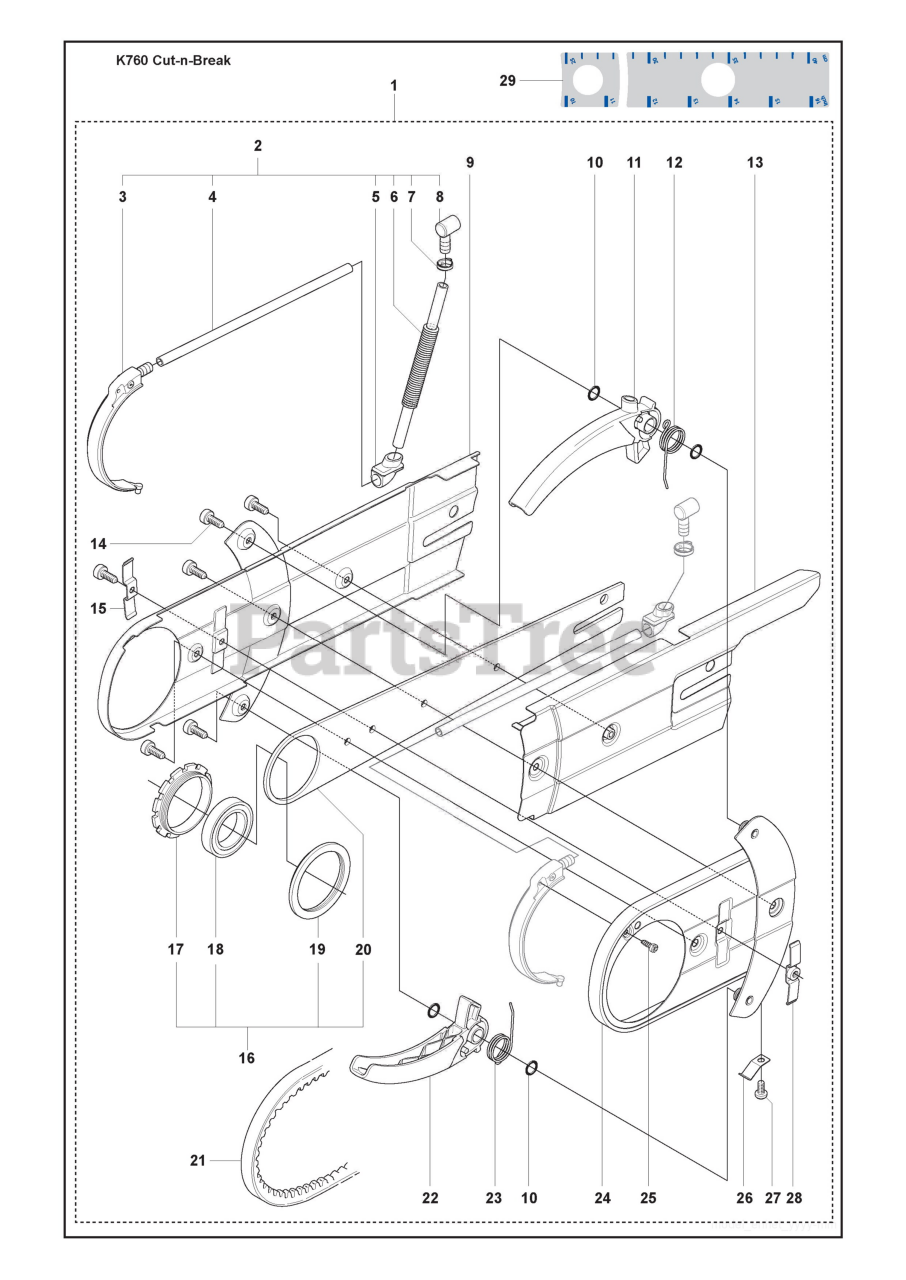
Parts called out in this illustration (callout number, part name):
1	Cutter Arm
2	Hose Assy
4	Hose
6	Protective Spring
7	Hose Clamp
9	Belt Guard
11	Belt Guard
13	Belt Cover
15	Deflection Limiter
16	Bar Assy
17	Bearing Cage
22	Blade Guard
24	Wear Protection
28	Deflection Limiter
